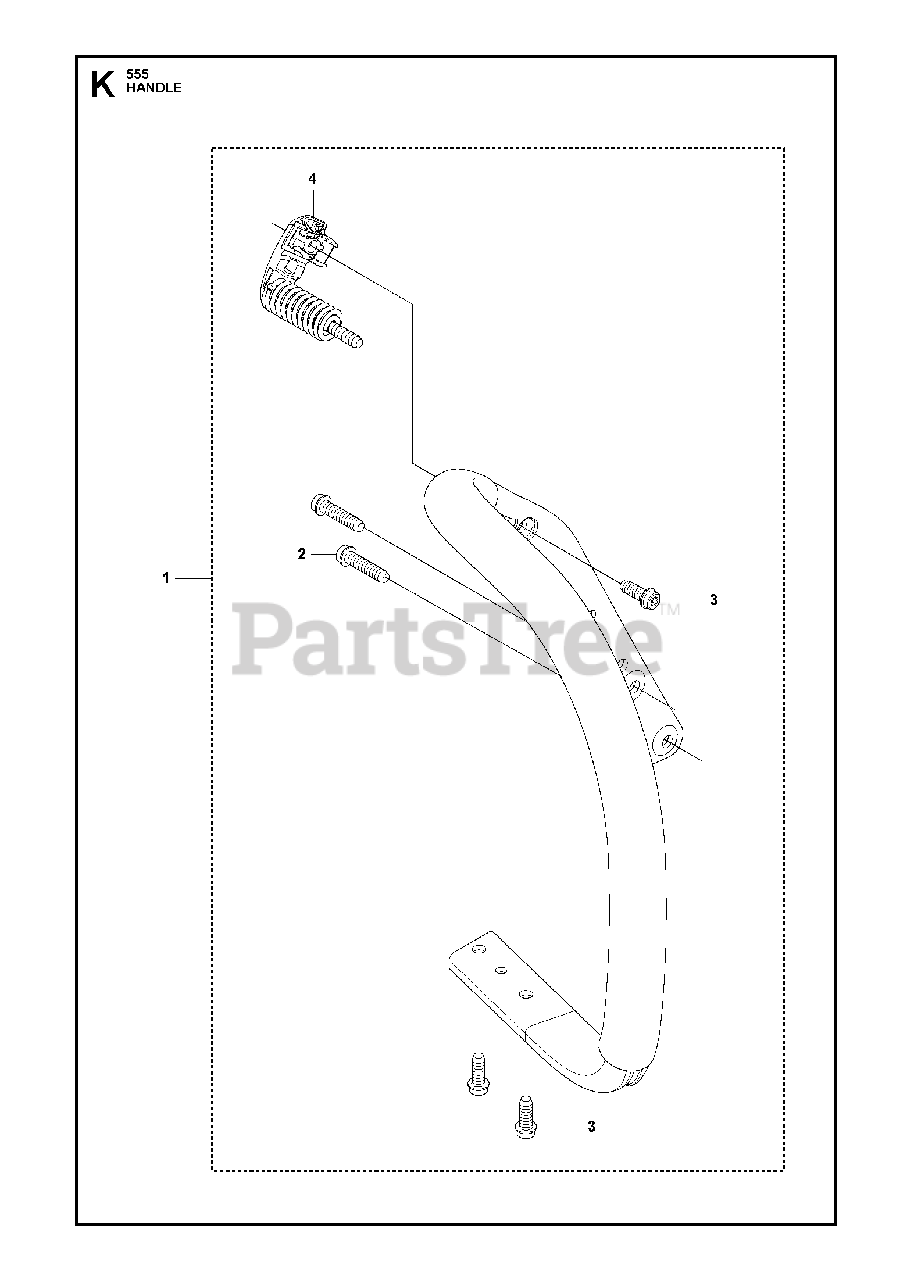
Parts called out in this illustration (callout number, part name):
1	FRONT HANDLE
2	SCREW
3	SCREW IHSCFT
4	ANTIVIBRATION ELEMENT
